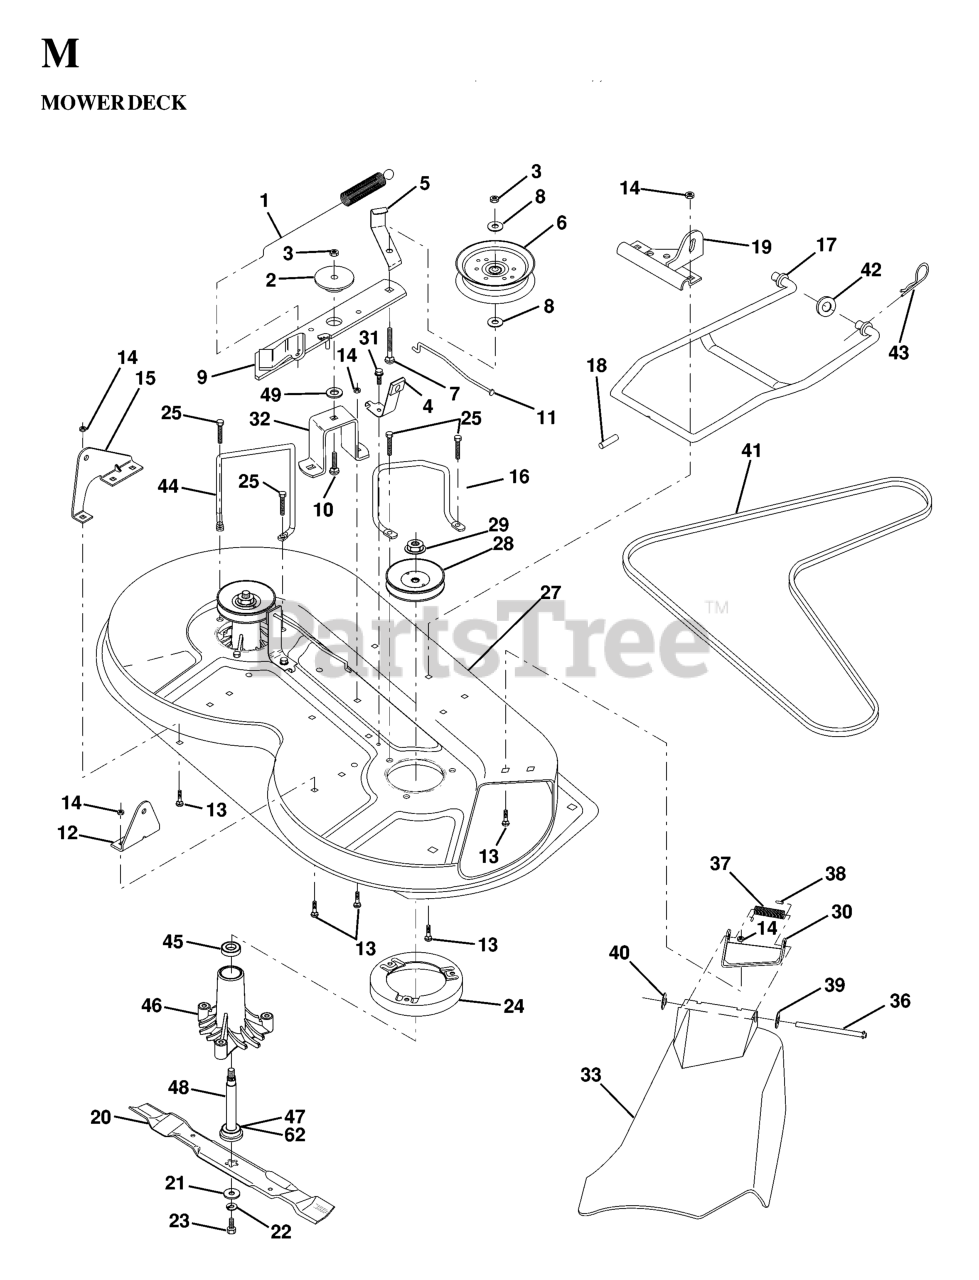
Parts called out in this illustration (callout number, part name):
1	SPRING-MOWER CLUTCH
2	SPACER RETAINER
4	BRAKE ASSEMBLY
5	IDLER BELT GUIDE
6	PULLEY.IDLER.FLAT.MOWER.BLK.PT
7	BOLT
8	WASHER
9	IDLER ARM ASSY
10	BOLT.3/8-14X1.25
12	BRKT LIFT REAR
13	RP BOLT 5/16-18 X3/4 ZN/YEL GR
14	LOCKNUT
15	BRKT LIFT REAR LH
16	BELT KEEPER
17	MOWER LINK STABILIZER
18	PIN GROOVE
19	BRKT LINK STABILIIZER
20	BLADE, HI-LIFT 36" PREMIUM
21	WASHER.BLADE
22	LOCKWASHER
23	BLADE BOLT
24	STRIPPER
25	SCREW
27	MOWER HOUSING
28	PULLEY, MANDREL
29	NUT
30	BRACKET ASM DEFLECTOR
31	Screw 5/16-18 x 1/2 Hex, Self Tapping 5/16-18 x 1/2
32	SUPT,IDLER ARM
33	DEFLECTOR
36	HINGE ROD
37	SPRING TORSION
38	CAP-SLEEVE LT
39	Washer 11/32 x 5/8 x 16 Ga SD
40	NUT PUSH M
41	BELT
42	WASHER
43	SPRING RETAINER
46	HOUSING.MANDREL.VENTED (MACHD)
47	BEARING.BALL.#6204.(MANDREL)
48	SHAFT ASM VENT
49	HARDENED WASHER
62	WASHER FELT
